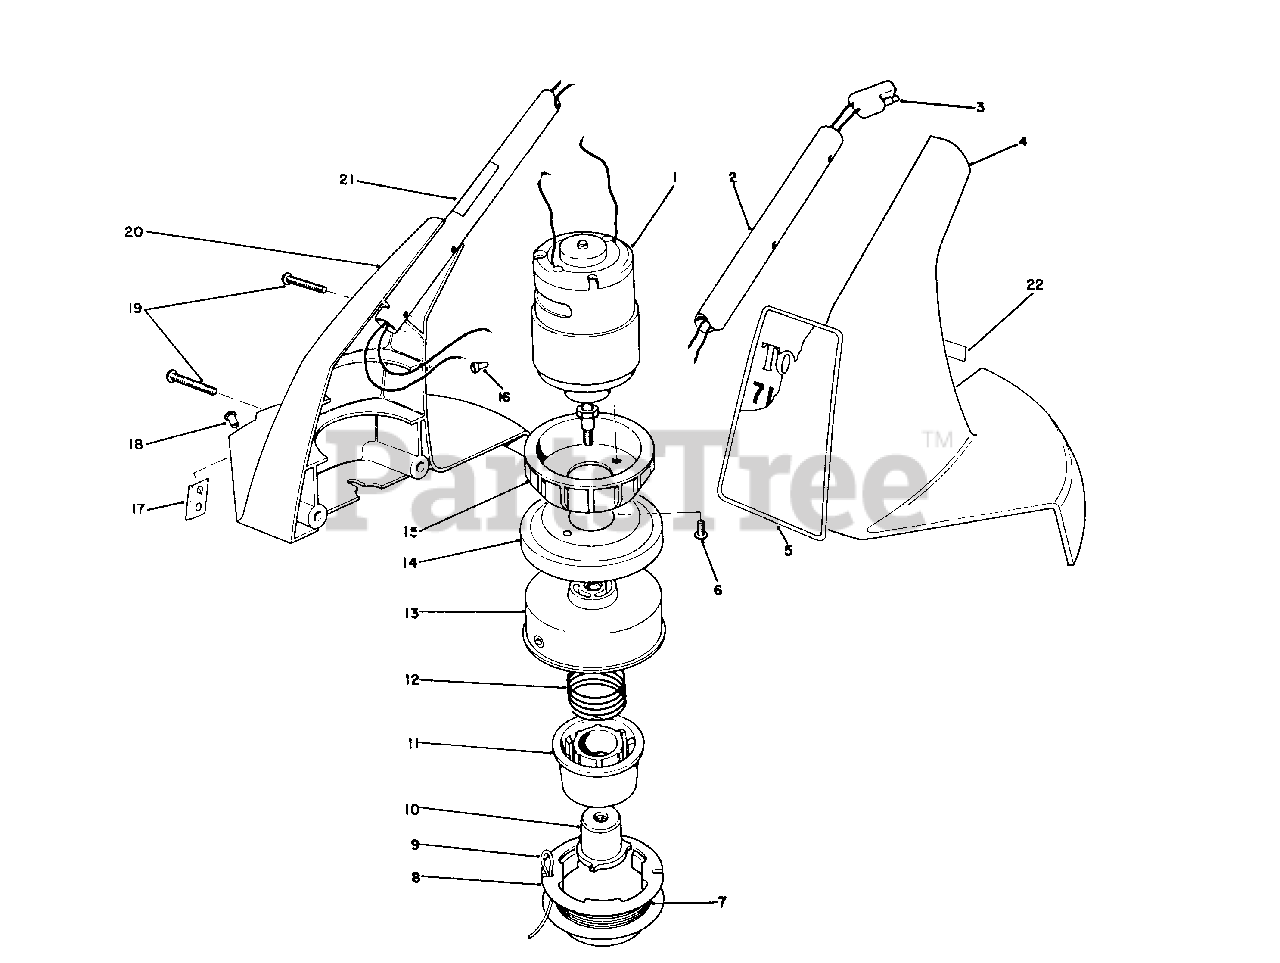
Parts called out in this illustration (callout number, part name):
3	Lower Wiring Harness
4	Housing-L.H.
5	Decal-Cordless
7	12 Ft. .050 dia. Cutting Line Prewound on Spool
8	Empty Spool
9	30 Ft. .050 dia . Cutting Line in Coil
12	Spring
13	Drum w/Eyelet
14	Cup-Drum
15	Heat Sink Casting
16	Wire Connector
17	Knife Blade
18	Rivet
20	R.H. Motor Housing (Incl. Ref. #17 & 18)
21	Decal-Serial Replacement
22	Decal-Made in Canada
